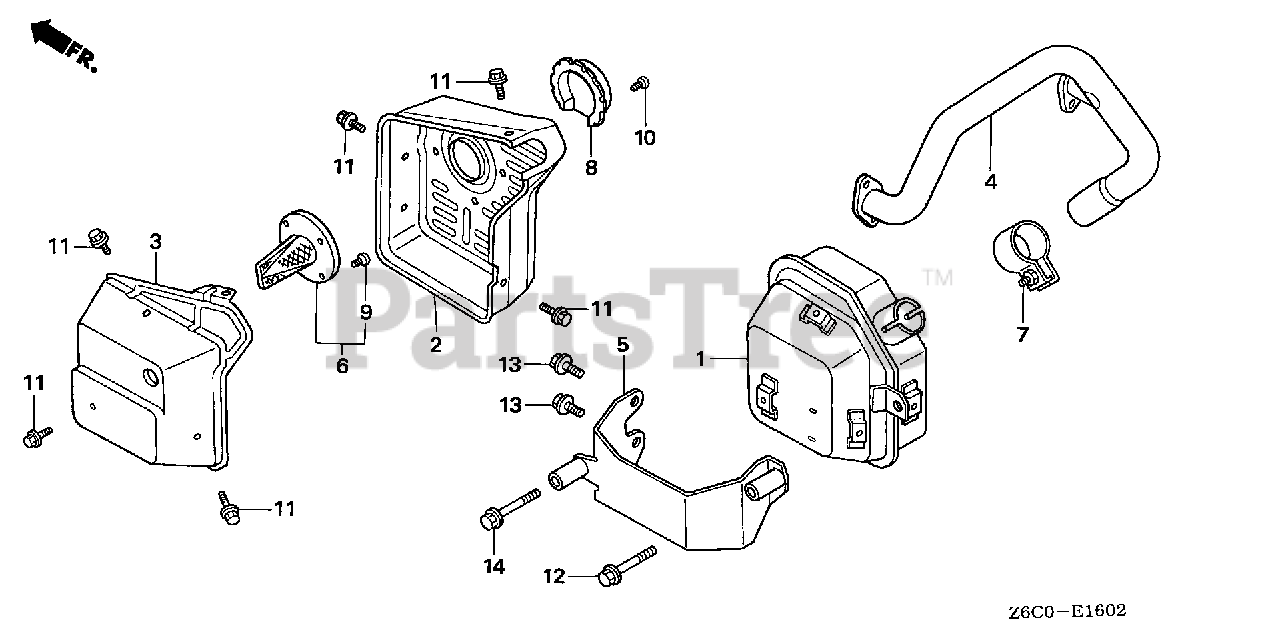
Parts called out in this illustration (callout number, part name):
1	MUFFLER COMP. (SIDE-L) (FUTABA) (SILVER MUFFLER)
2	PROTECTOR, MUFFLER (SIDE-L)
3	PROTECTOR, RR. MUFFLER (SIDE-L)
4	PIPE COMP., EX. (SIDE-L)
5	STAY, MUFFLER (SIDE-L)
6	ARRESTER, SPARK (SIDE)
7	BAND ASSY. (FOR BLACK MUFFLER) (NOT AVAILABLE)
9	SCREW (NELSON) (SCREW UNAVAILABLE SEPARATELY. ORDER DEFLECTOR KIT.)
11	BOLT, FLANGE (6X8)
12	BOLT, FLANGE (6X50)
13	BOLT, FLANGE (8X14)
14	BOLT, FLANGE (8X50)
